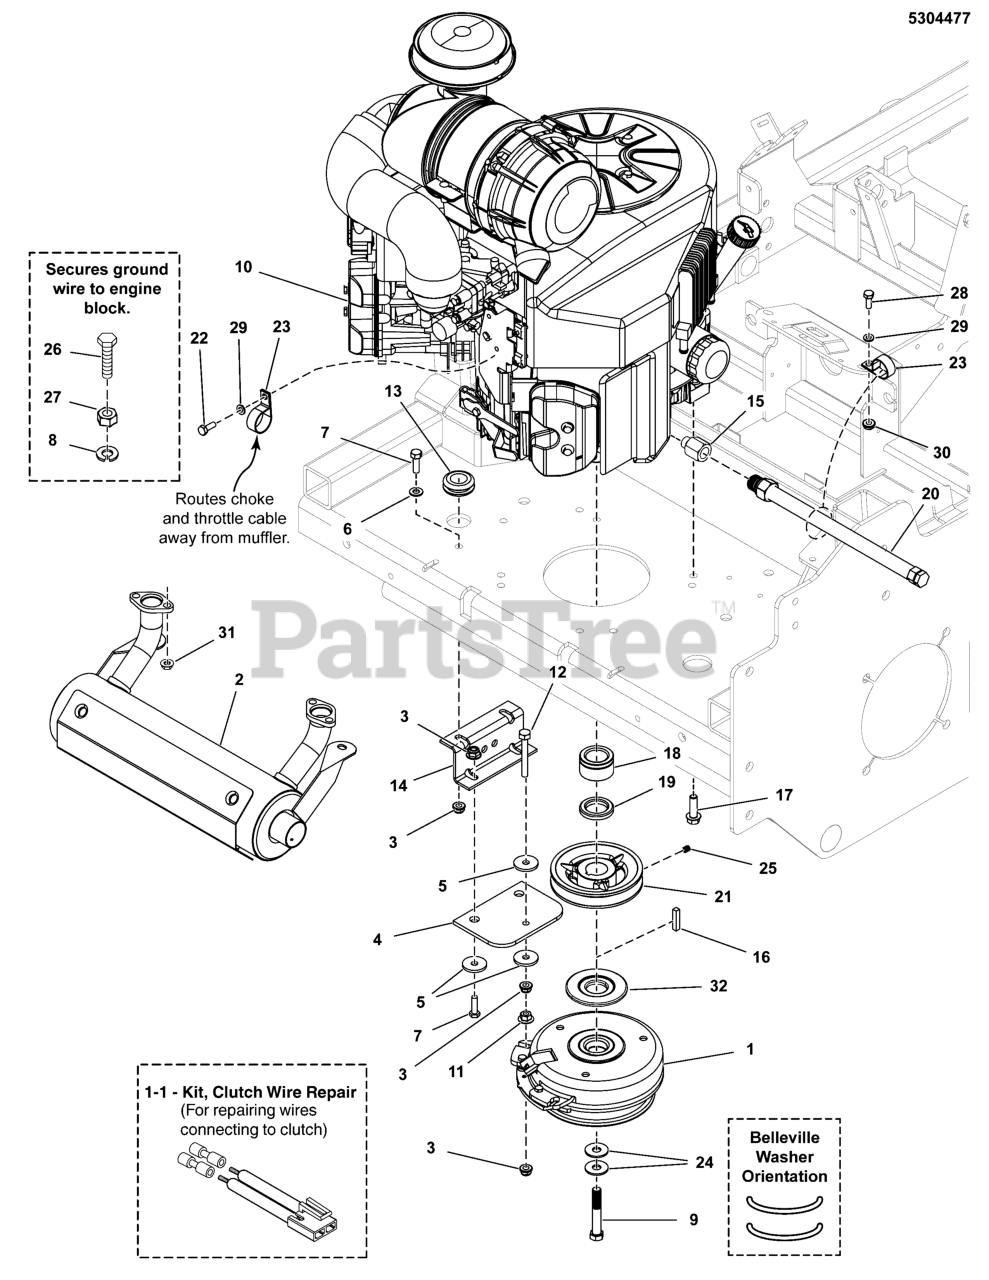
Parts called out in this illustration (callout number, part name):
1	CLUTCH, 250 FT-LBS, WATER GUARD
1-1	KIT, CLUTCH WIRE REPAIR
2	MUFFLER, 27HP KAWASAKI, 5" CAN
3	NUT, 5/16-18 HEX NYLOCK FLANGE NUT
4	CLUTCH ANCHOR PAD
5	WASHER, .34 X 1.25 X 10 GA
6	WASHER, 5/16" SAE
7	BOLT, 5/16-18 X 1" GRD5 YZ
8	WASHER, 5/16 LOCK CZ
9	BOLT, CRANKSHAFT, 7/16-20 X 3-1/4, GD 8
11	NUT, 5/16-18 HEX SERRATED FLANGE (LARGE)
12	BOLT, 5/16-18 X 2-1/2 GD5 TFL, CZ
13	GROMMET, 7/8"ID, 1/4" THICK STK
14	ANCHOR, CLUTCH - BLK
15	ADAPTER, Oil Drain
16	KEY, 1/4" SQ. X 1-1/4
17	BOLT, HEX FLG, SER, GD5 3/8-16 X 1-1/4" PACH CZ
18	SPACER, 1.13 X 1.75 X 1.03, CZ
19	SPACER, 1.13 x 1.75 x .25
20	HOSE, OIL DRAIN
21	PULLEY, 4.75 OD X 1-1/8 BORE, BC-48
22	CAPSCREW, HEX HEAD M6-1.0 X 14MM
23	CLAMP, VINYL INSULATED, 1.00
24	BELLEVILLE WASHER, 1.1875 X .442 X .098
25	SET SCREW, 5/16-18 X 3/8, KNURL, W/PATCH
26	BOLT, M8-1.25 X 20 MM GD 8.8
27	NUT, HEX, M8-1.25, CZ, GD 8.8
28	BOLT, 1/4"-20 X 3/4" GD5 YZ
29	WASHER, 1/4 SAE
30	NUT, 1/4-20 HEX SERR. FLANGE
31	NUT, M8-1.25 Hex Serrated Flange
32	WATER GUARD, WARNER C 250 FT-LBS CLUTCH
